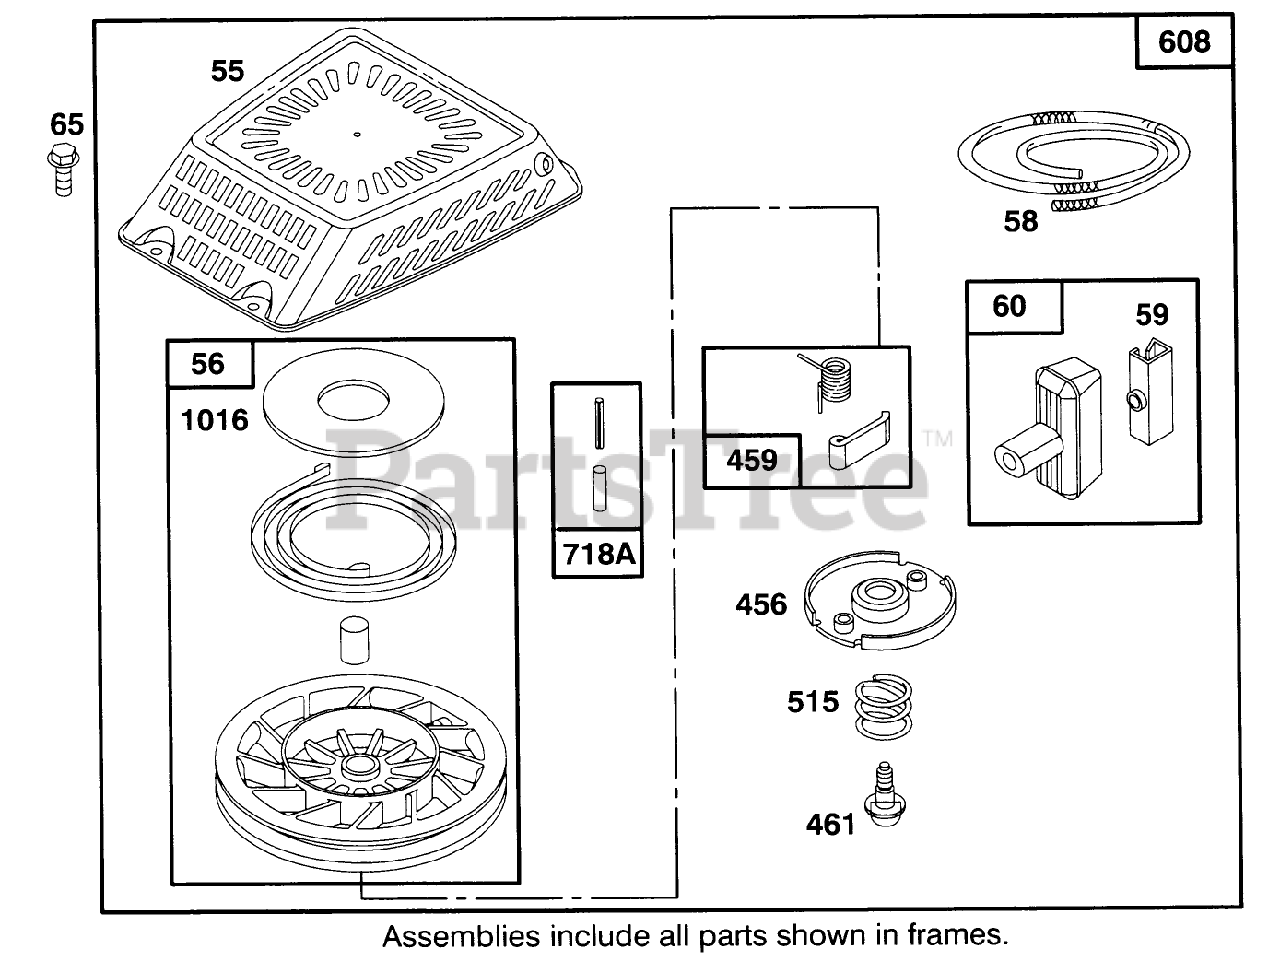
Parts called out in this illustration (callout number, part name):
60	HANDLE-REWIND STARTER
456	RETAINER - SPRING
515	SPRING - RETAINER
